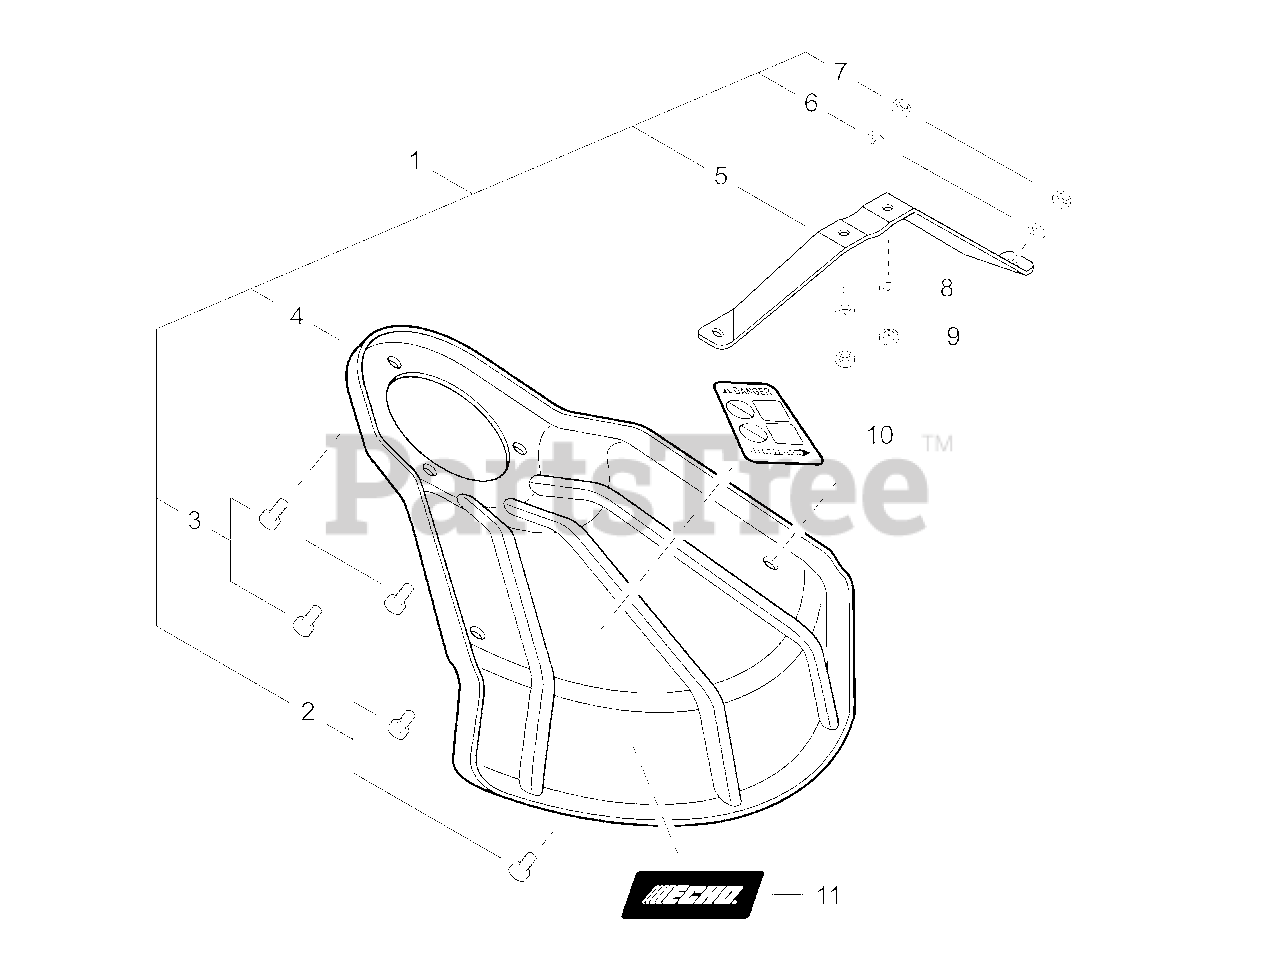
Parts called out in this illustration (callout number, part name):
1	SHIELD ASSY, METAL DEBRIS
2	SCREW 5×8
3	SCREW 5×10
4	SHIELD, METAL DEBRIS
5	BRACKET, SHIELD MOUNTING
6	WASHER, SPRING 5
7	NUT M5
8	WASHER, SPRING 5
9	NUT M5
10	LABEL, DANGER
11	LABEL, ECHO
